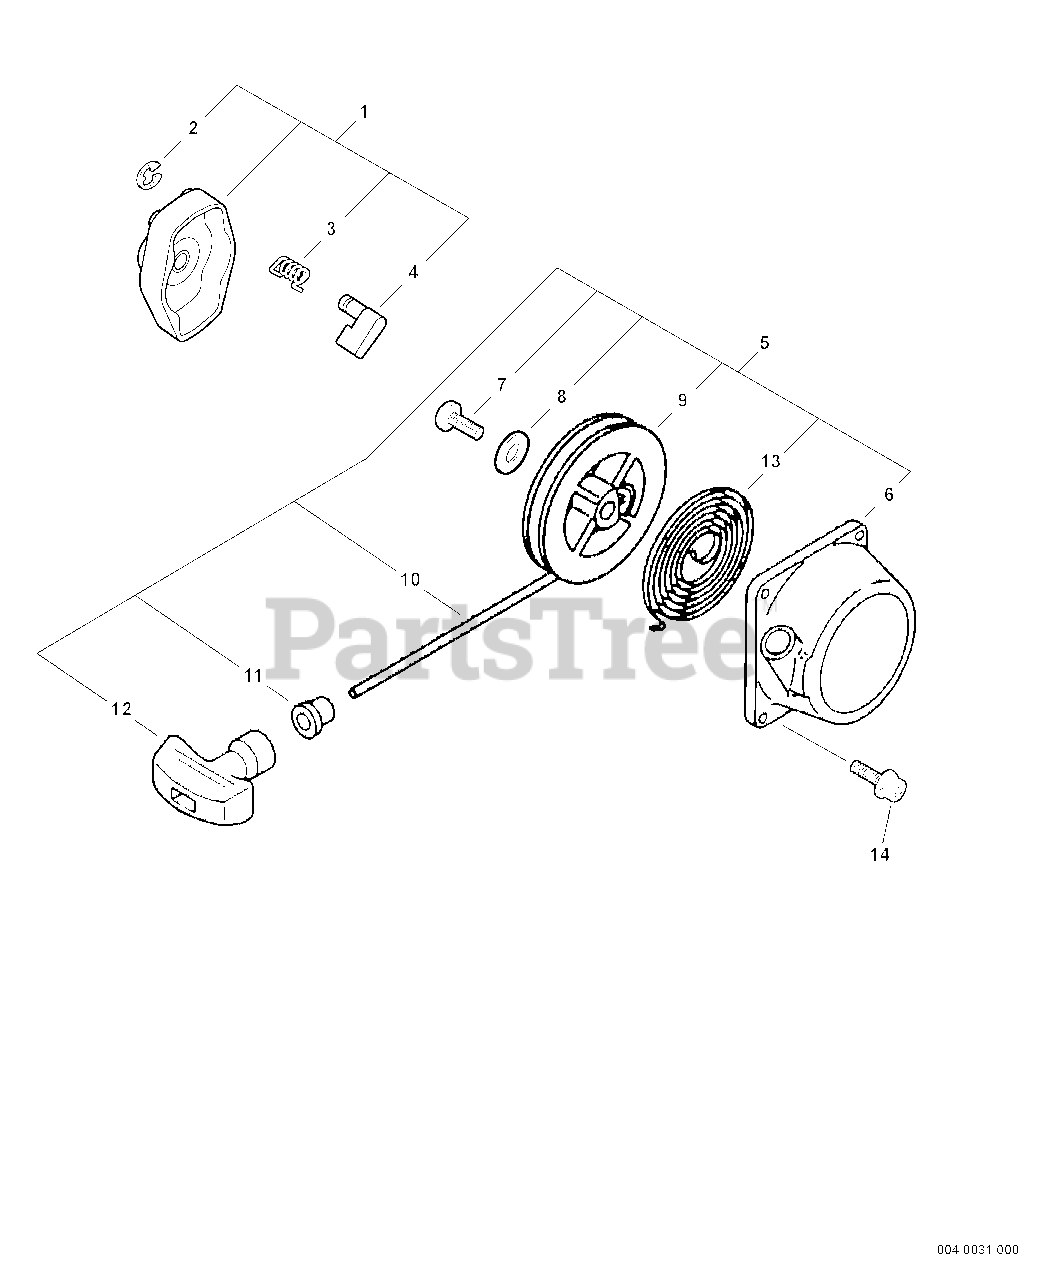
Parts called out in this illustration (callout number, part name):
1	PAWL ASSY, STARTER
2	E-RING 4
3	SPRING, RETURN
4	PAWL, STARTER
5	STARTER ASSY
6	CASE, RECOIL STARTER
8	WASHER
9	REEL, ROPE
10	ROPE, STARTER 3.8×1400
11	GUIDE, ROPE
12	GRIP, STARTER
13	SPRING, RECOIL
14	BOLT 4×18
